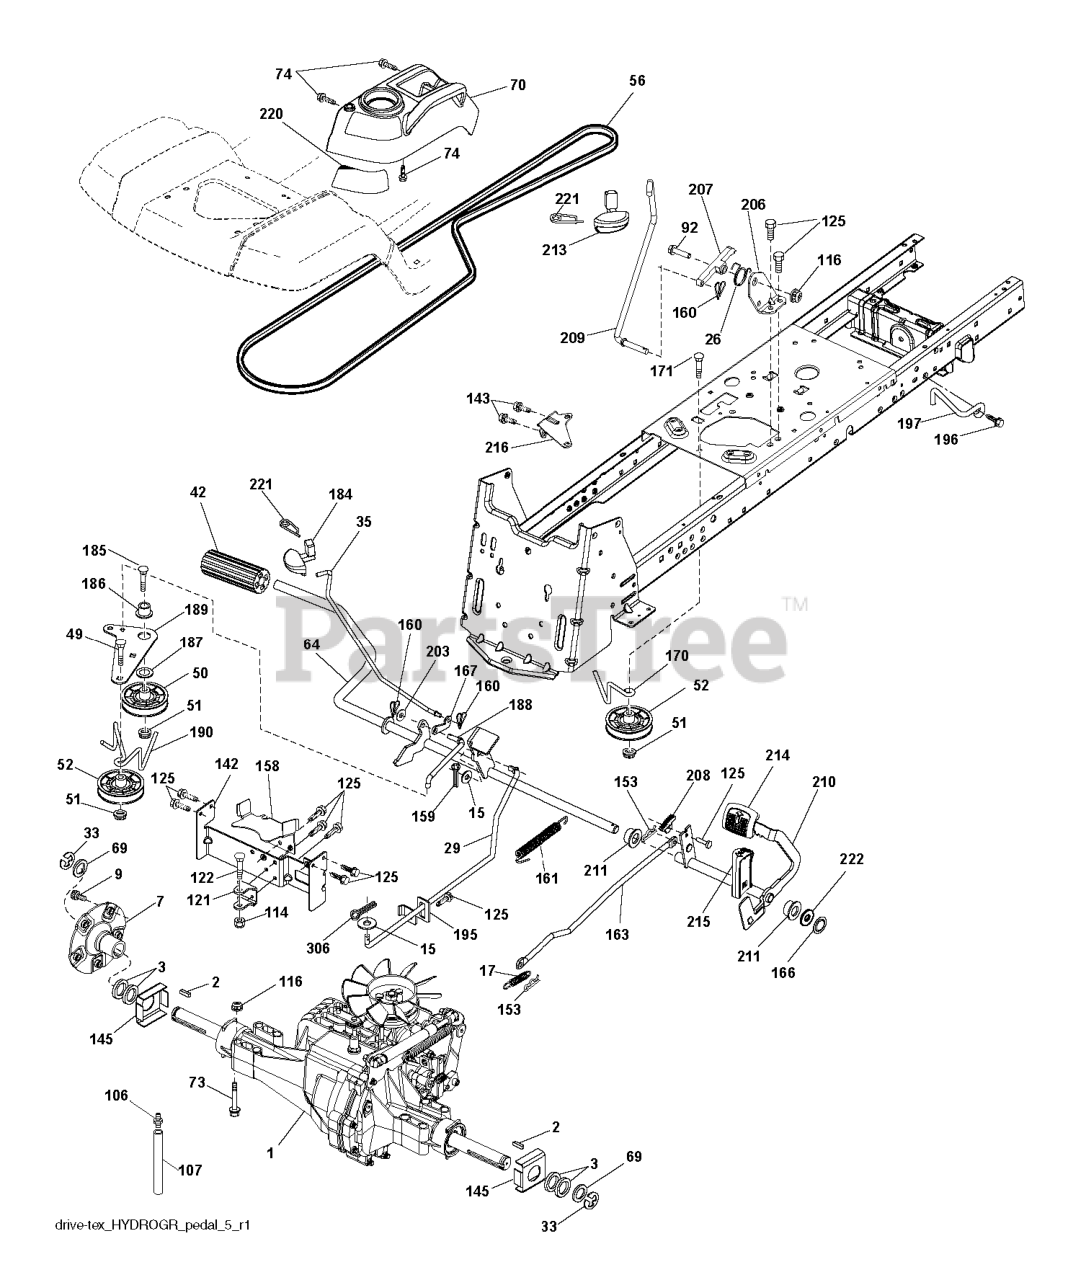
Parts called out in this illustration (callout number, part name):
2	KEY 1/4 X 2.5
7	HUB.ASM.WHEEL.REAR.23"TEX
15	WASHER
17	SPRING.BRAKE.HG3000/3500
26	SPRING.RETURN.CRUISE
29	ROD.BRAKE.HG3000/3500
33	E RING HYT
35	ROD.BRAKE.PARKING.GT.H
42	PEDAL COVER T
50	IDLER.FLAT.910.OFFSET
51	NUT LOCK FLG 3/8-16 UNC
52	IDLER.V-GROOVE.910.OFFSET
56	BELT.V.GROUND.DRIVE
64	SHAFT.ASM.PEDAL.BRK.CNTR
70	RP CONSOLE.ASM.PCH.W/TB
73	BOLT HEX FLGHD 5/16-18X3 GR. 5
74	SCREW.HI-LO.CONSOLE
92	BOLT
106	CAP, VENT ASSY
114	NUT.71038.31-18.HEX.NYLOCK
116	NUT LOCK HEX FLANGE 5/16-18
121	BRACKET STRAP TORQUE
122	BOLT.5/16-18X2.5
125	SCREW
142	STRAP.TORQUE.HG3000/K46
143	Screw 5/16-18 x 1/2 Hex, Self Tapping 5/16-18 x 1/2
145	WASHER.AXLE.FLANGE.HG-3000
153	RETAINER M
158	KEEPER BELT
159	COTTER PIN
160	RETAINER CLIP
161	SPRING, RETURN LT
166	NUT.PUSH.625
167	LATCH.BRAKE.SPRING
170	KEEPER.V-IDLER.CENTER.
184	HANDLE.PARKG.BRK.HUSQ X667
186	SPACER.RETAINER
187	WASHER 12/32X2X10GA
188	RP.LINK.CLUTCH.GROUND.DRIVE
189	BELLCRANK.GROUND.DRIVE.TEX.
190	KEEPER.BELLCRANK.DRIVE
195	RETAINER.ROD.BRAKE.HG3000.TEX
196	SCREW 3/8-16X1
197	BRKT.ANIT-ROTATION.CLUTCH
203	WASHER
206	BRKT.MOUNT.LATCH.CRUIS
207	LATCH.CONTROL.CRUISE
208	GEAR.SECTOR.CONTROL.CR
209	ROD.CONTROL.CRUISE.GT.
210	ROCKER.ASM.PEDAL.CONTR
211	BEARING.NYLON
213	KNOB.CONTROL.CRUSIE.HU
214	PEDAL.FORWARD.PAD.TEX
215	PEDAL.REVERSE.TEX.GT.4
216	BRACKET.PULLEY.IDLER.W/TEX
220	REFLECTOR.RH.TEX GT
221	RETAINER.SPRING.CLIP.H
222	WASHER
306	PIN COTTER
